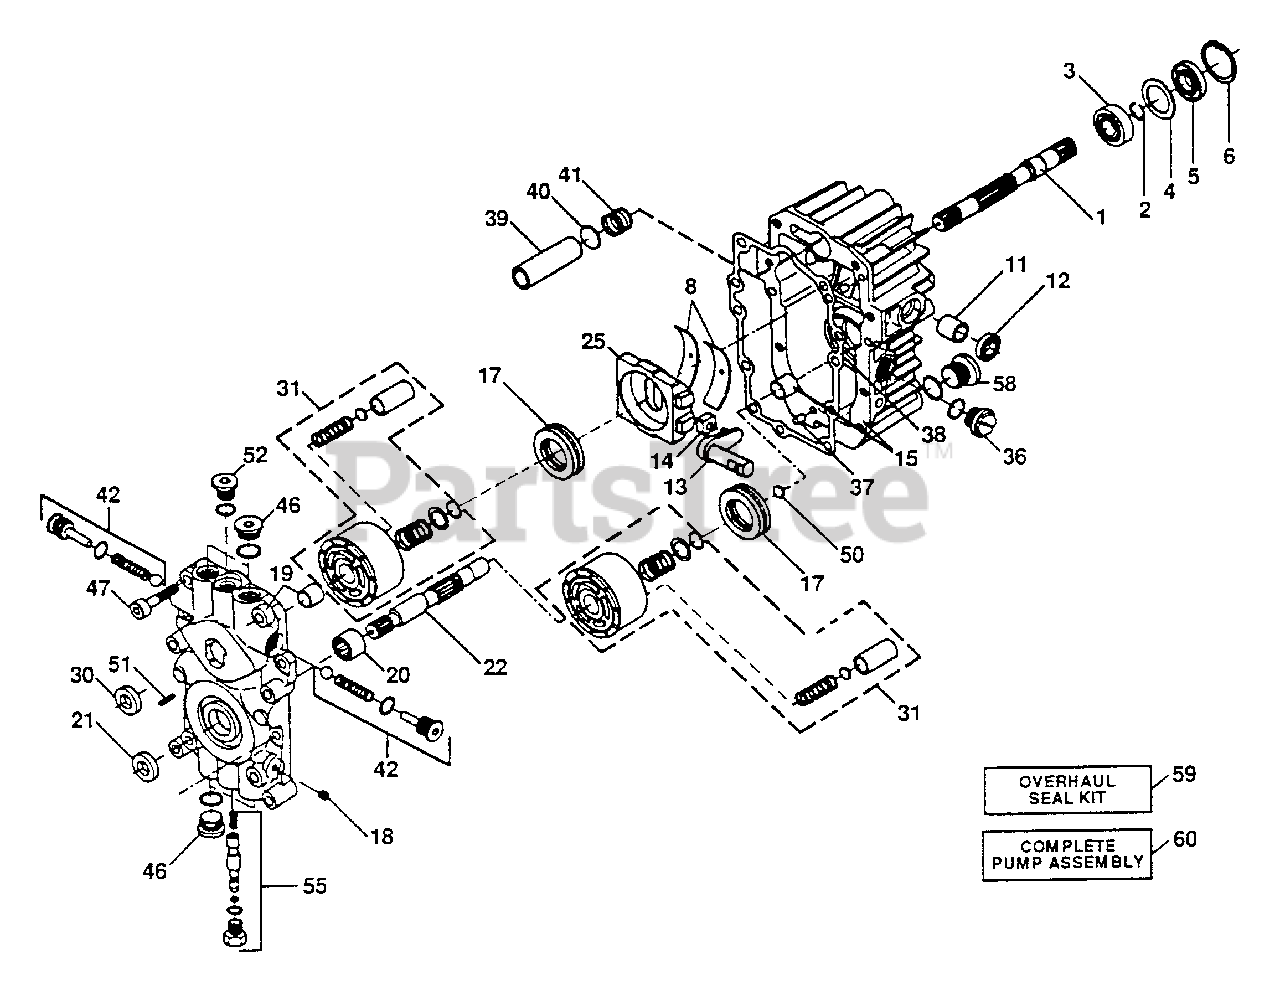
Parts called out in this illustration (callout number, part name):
1	Shaft, Pump
2	Ring, Retaining
3	Bearing, Ball
4	Spacer
5	Seal, Lip
6	Ring, Retaining
8	Bearing, Cradle
11	Bearing, Journal
12	Seal, Lip
13	Arm, Trunnion
14	Guide, Slot
15	Housing Kit, Transmission
17	Bearing, Thrust, Ball
18	Plug, Pipe
19	Center Section Kit
20	Bearing, Needle
21	Seal, Lip
22	Shaft, Motor
25	Swashplate, Variable
30	Seal, Lip
31	Block Kit, Cylinder
36	Plug. Plastic
37	Pin, Stainless, Headless
38	Gasket, Center Section
40	Washer, Thrust
41	Spring, Helical, Compression
42	Check Valve Kit
46	Plug, Stainless, Threaded
47	Screw, Socket Head, Cap
50	Washer, Thrust
51	Pin, Spiral
52	Plug, Stainless, Threaded
55	Bypass Valve Kit
58	Plug, Stainless, Threaded
59	Overhaul Seal Kit. BDU-10
60	Pump Assembly, Complete
